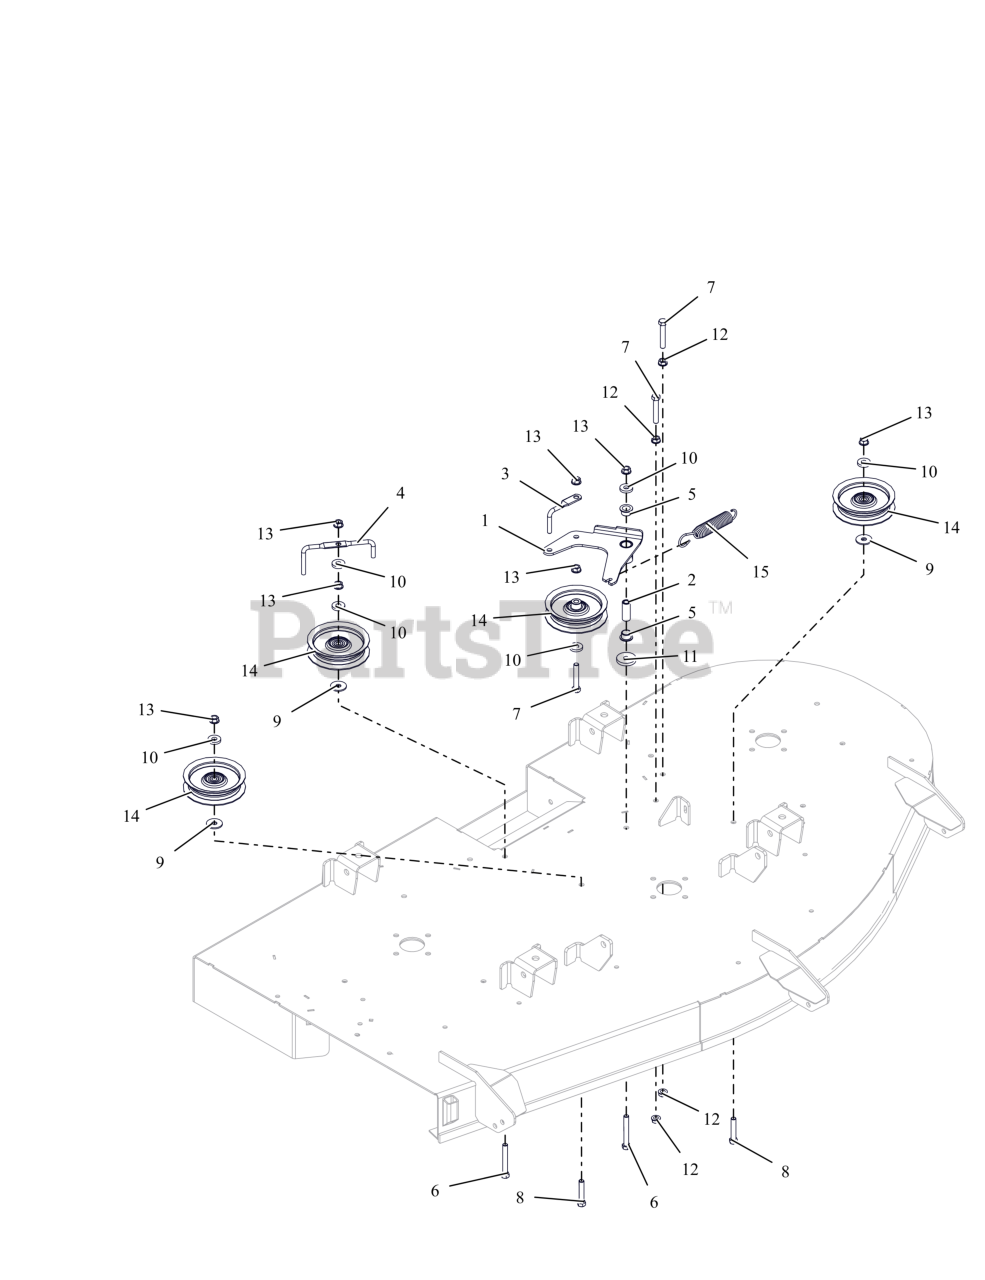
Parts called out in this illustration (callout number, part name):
1	WLDMT, IDLER ARM-42"
2	SPACER, .375IDX.625ODX1.66 PM
3	WIREFORM-BELT FINGER
4	BELT FINGER
5	BSHG-FLG, .625X.750X.500X1.00
6	BLT, HEX .38-16X2.75 G5 ZCC
7	BLT,HEX .38-16X2.25 G5 ZCC
8	BLT,HEX .38-16X2.00 G5 ZCC
9	WSHR FL STL .406X1.25X.10ZC120
10	WSHR, FLT .406X1.00X.188 ZCC
11	WSHR, FLT .406X1.50X.245 ZCC
12	NUT, SPNLK-FLG .38-16 G5 ZCC
13	NUT-LK-CTR-FLG .375-16 GF ZCC
14	IDLER, FLAT - 4.06" X .75"
15	SG-TENS .135X.98X6.0 WLD 62
